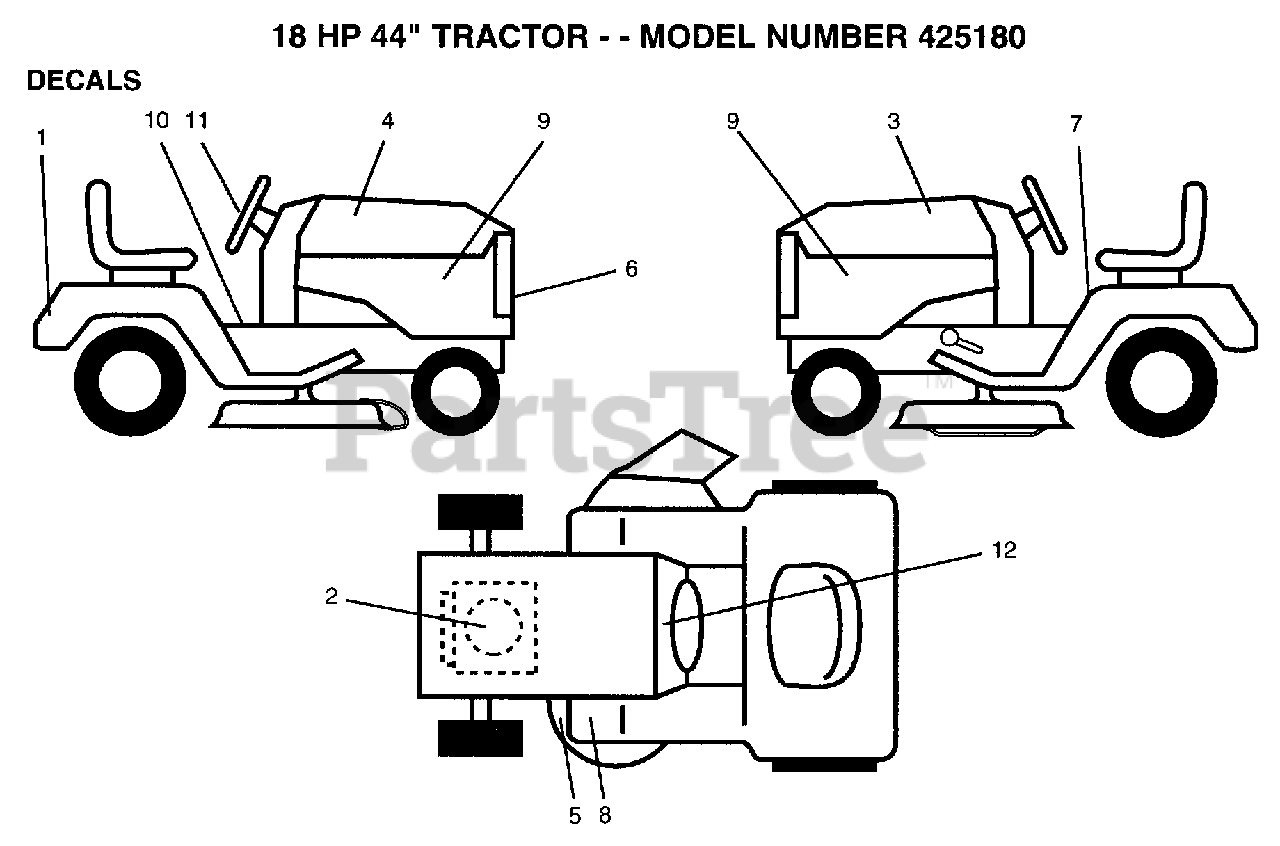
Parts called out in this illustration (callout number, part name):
2	"DECAL,HP ENGINE"
3	DECAL HOOD LH
5	"DECAL.V.BELT.44"""
6	DECAL.GRILL.YARDP
7	DECAL
9	DECAL.PANEL.SIDE
10	DECAL BRAK PARK
11	DECAL.INS.WHL.STG
12	DECAL.DASH.INST.
